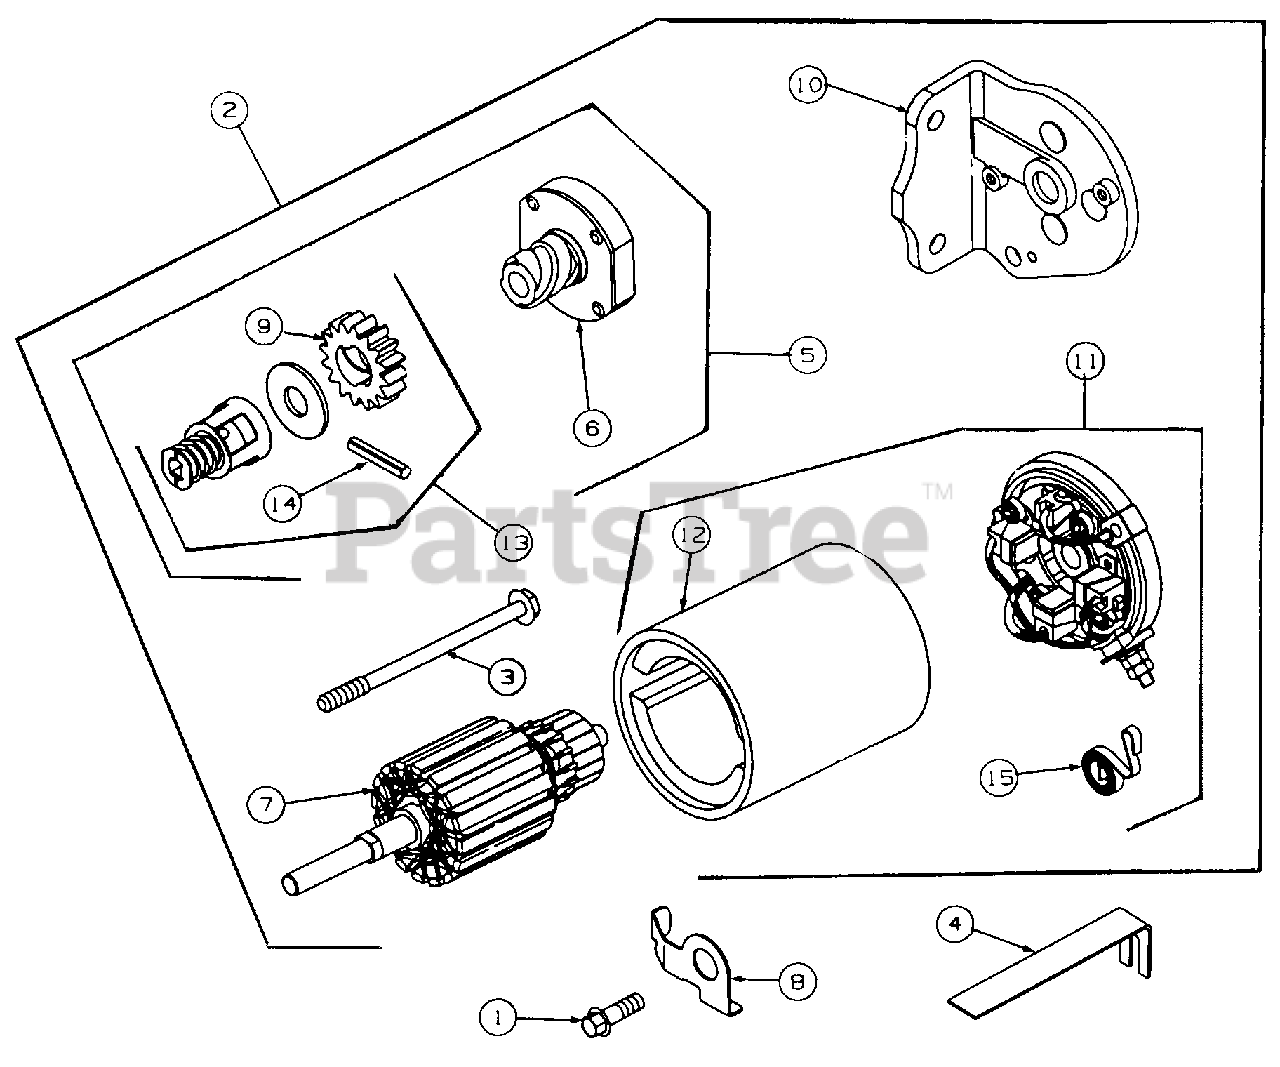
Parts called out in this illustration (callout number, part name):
1	Screw, Hex
2	Starter Assembly, Motor
3	Screw, Hex
4	Strap, Starter
5	Starter, Drive Group
6	Clutch Assembly
7	Armature Assembly
8	Clip, Wire
9	Gear, Starter
10	Drive End Cap Assembly
11	Cap Assembly, Commutator End
12	Housing Assembly
13	Kit, Gear
14	Pin, Roll
15	Spring, Brush
